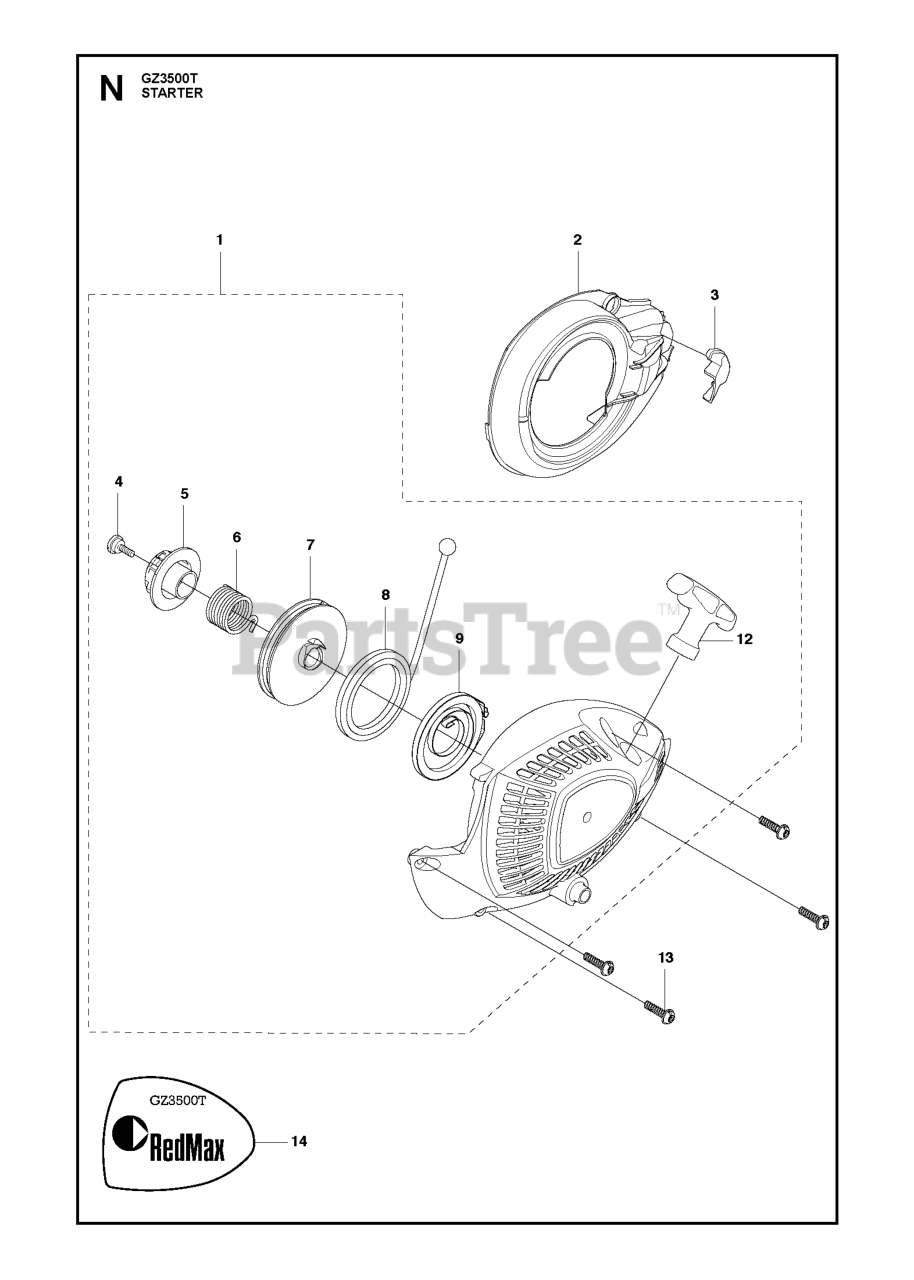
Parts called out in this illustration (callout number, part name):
1	STARTER ASSY
2	COVER FAN
3	GUIDE, DF (GZ3500T)
5	CAM, PLATE
9	SPRING ASSY
